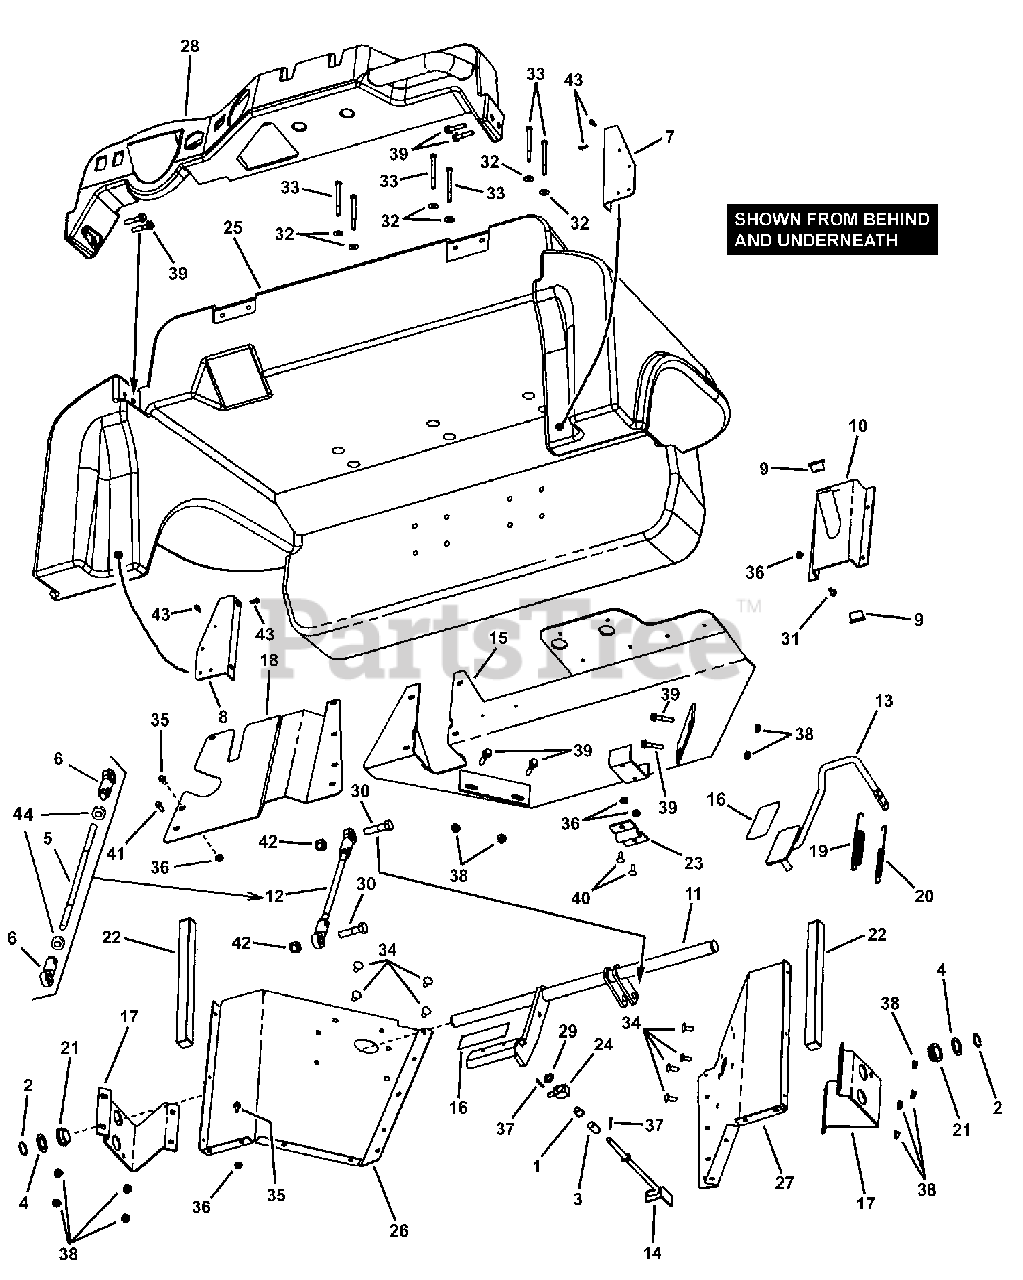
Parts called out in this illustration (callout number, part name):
1	BUSHING, Flange .381 x .625 x .62
2	RING, 1.00 Dia. External Retaining
3	SPRING
4	BUSHING, 14 Gage Machine
5	ROD, Upper CVT Brake
6	ROD END, Female 1/2-20 thread
7	KICK PLATE, RH
8	KICK PLATE, LH
9	BEARING, .750 I.D.
10	SUPPORT ASSEMBLY, Column
11	PEDAL ASSEMBLY, Brake CVT
12	ASSEMBLY, Upper Brake Rod (Includes Ref. Nos. 5, 6 & 44)
13	PEDAL ASSEMBLY, Throttle Pedal
14	ROD ASSEMBLY, Brake Switch
15	SUPPORT ASSEMBLY, Steering
16	PEDAL GRIP
17	BRACKET, Brake Support, Used on Turf Cruiser Models 85632 & 85668
17	BRACKET, Brake Support, Used on Trail Cruiser Model 85903
18	PEDAL SHIELD, Used on Turf Cruiser Models 85632 & 85668
18	PEDAL SHIELD, Used on Trail Cruiser Model 85903
19	SPRING, Throttle Pedal Return
20	SPRING, Inner Throttle Return
21	BEARING, 1 I.D.
22	GASKET, Closed Cell, Adhesive Back
23	PIVOT BRACKET, Throttle
24	SWIVEL, Brake Rod
25	FENDER, UV-2
26	FIREWALL, LH, Used on Turf Cruiser Models 85632 & 85668
26	FIREWALL, LH, Used on Trail Cruiser Model 85903
27	FIREWALL, RH, Used on Turf Cruiser Models 85632 & 85668
27	FIREWALL, RH, Used on Trail Cruiser Model 85903
28	DASH, UV-2
29	WASHER, 3/8 SAE Flat
30	CAPSCREW, Hex Head, 1/2-13 x 2-3/4 GR 5
31	SCREW, Pan Head Machine 1/4-20 x 1/2
32	WASHER, .281 x .750 x .051 Flat
33	CAPSCREW, Hex Head, G1/4-20 x 3 Hex Head, GR 5
34	CARRIAGE BOLT, 5/16-18 x 3/4 GR 5
35	SCREW, Hex Flange Lock, 1/4-20 x 1/2 GR 5
36	NUT, Hex Flange Lock, 1/4-20 GR 5
37	COTTER PIN, 1/8 x 3/4
38	NUT, Hex Flange Lock, 5/16-18 GR 5
39	BOLT, Hex Flange Lock, 5/16-18 x 1-1/2 GR 5
40	CARRIAGE BOLT, 1/4-20 x 3/4
41	SCREW, Hex Washer Self-Tap, 1/4-20 x 5/8
42	NUT, Hex Nyloc, 1/2-13
43	SCREW, #10 x 5/8, HiLo Nail Point
44	NUT, Hex Jam, 1/2-20 GR 5 or B
